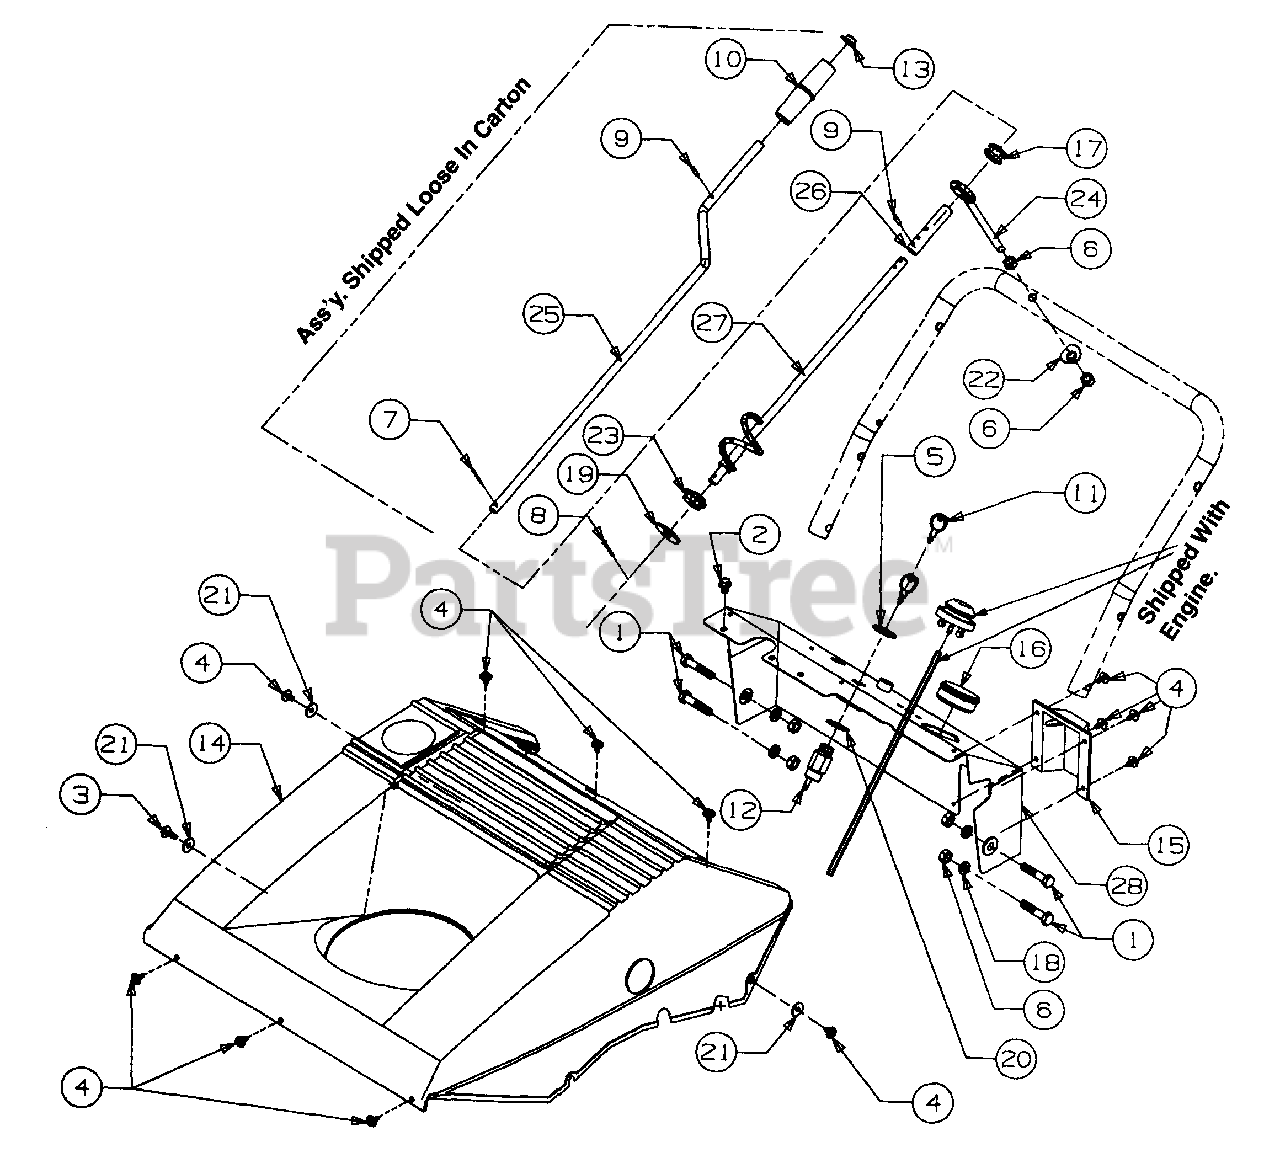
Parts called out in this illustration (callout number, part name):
1	Screw - Hex
2	Screw - Hex Washer
3	Screw - Hex
4	Screw - Hex
5	Nut - Jam
6	Nut - Hex
7	Pin - Cotter
8	Pin - Cotter
9	Pin Roll
11	Key - Ignition
12	Switch
13	Cap - Push
14	Shroud - Black
15	Cover - Choke
16	Plug - Insert
17	Grommet - Rubber
18	Washer - Lock
19	Washer - Flat
20	Washer - Lock-Internal
21	Washer - Flat
22	Washer - Saddle
23	Bushing - Hex
24	Eyebolt - Chute Crank
26	Spacer
27	Crank - Chute 13.5" Lg.
